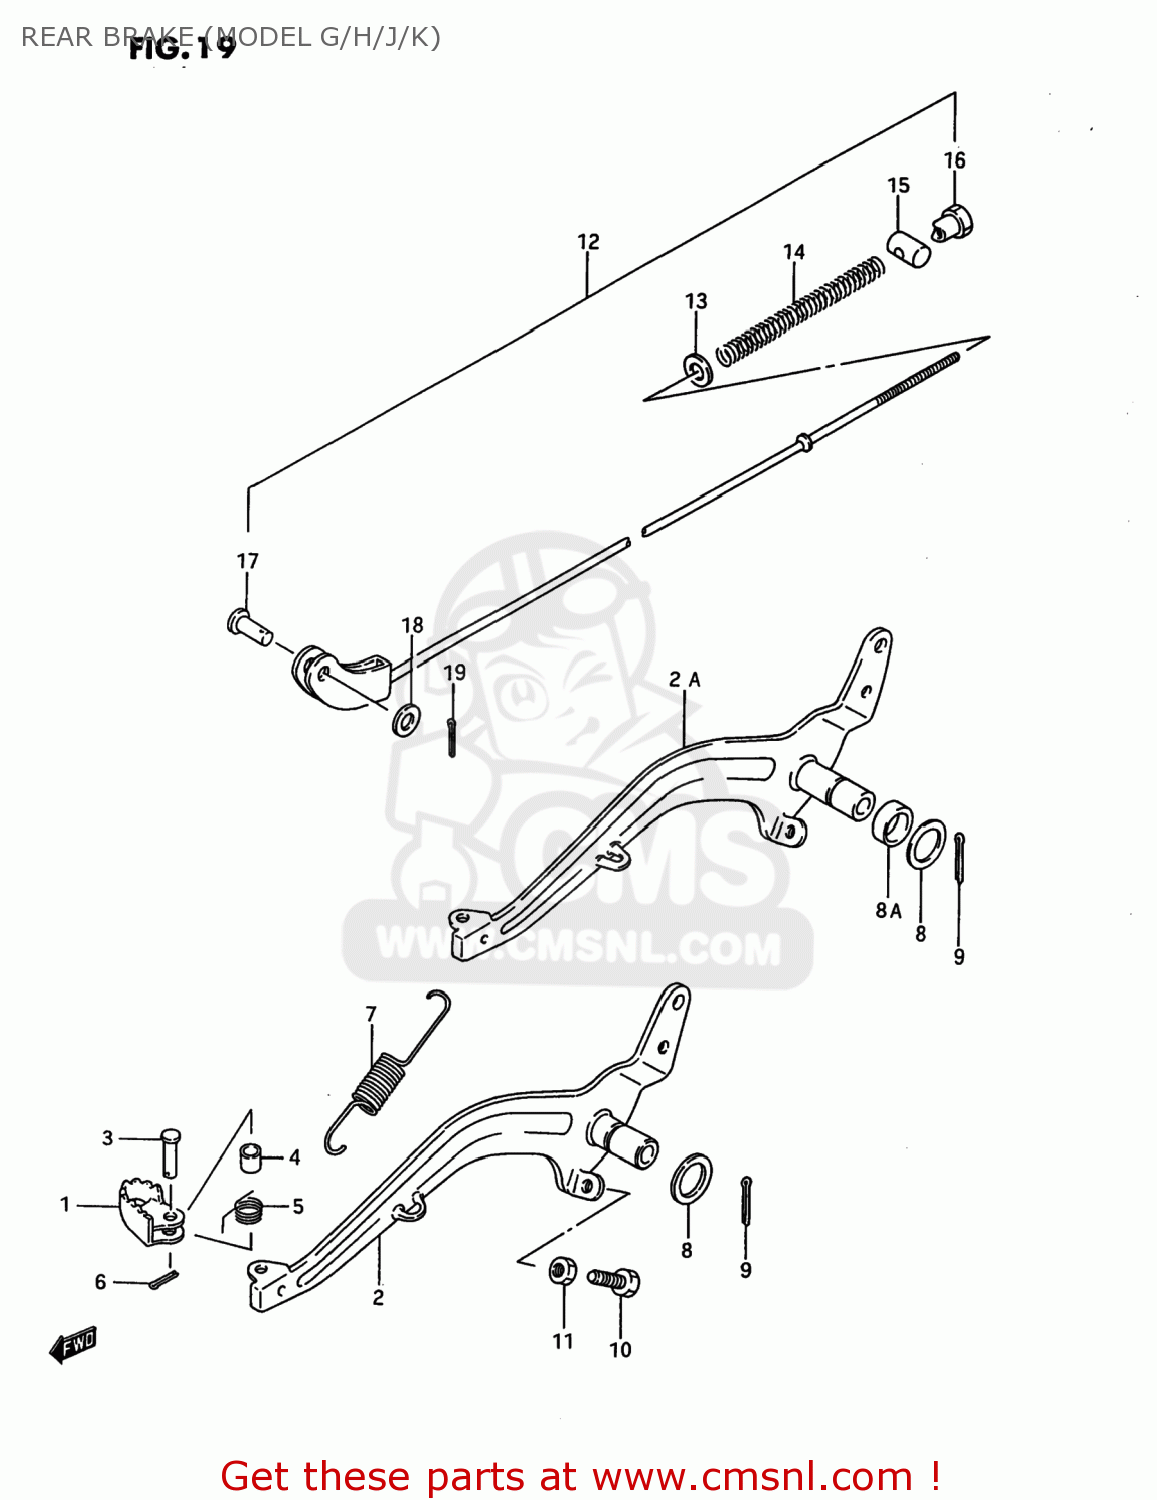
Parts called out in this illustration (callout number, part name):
1	PEDAL,BRAKE
2	ARM,BRAKE PEDAL
2A	ARM, BRAKE PEDAL
3	PIN
4	SPACER(9.2X9X6.5)
5	SPRING
6	PIN
7	SPRING
8	WASHER(15.5X26X2.3)
8A	SPACER
9	COTTER PIN
10	SCREW(6X23)
11	NUT 6MM
12	ROD ASSY,RR BRAKE
13	WASHER
14	SPRING
15	PIN(11X18)
16	NUT (6MM)
17	PIN
18	WASHER
19	PIN 20X20
